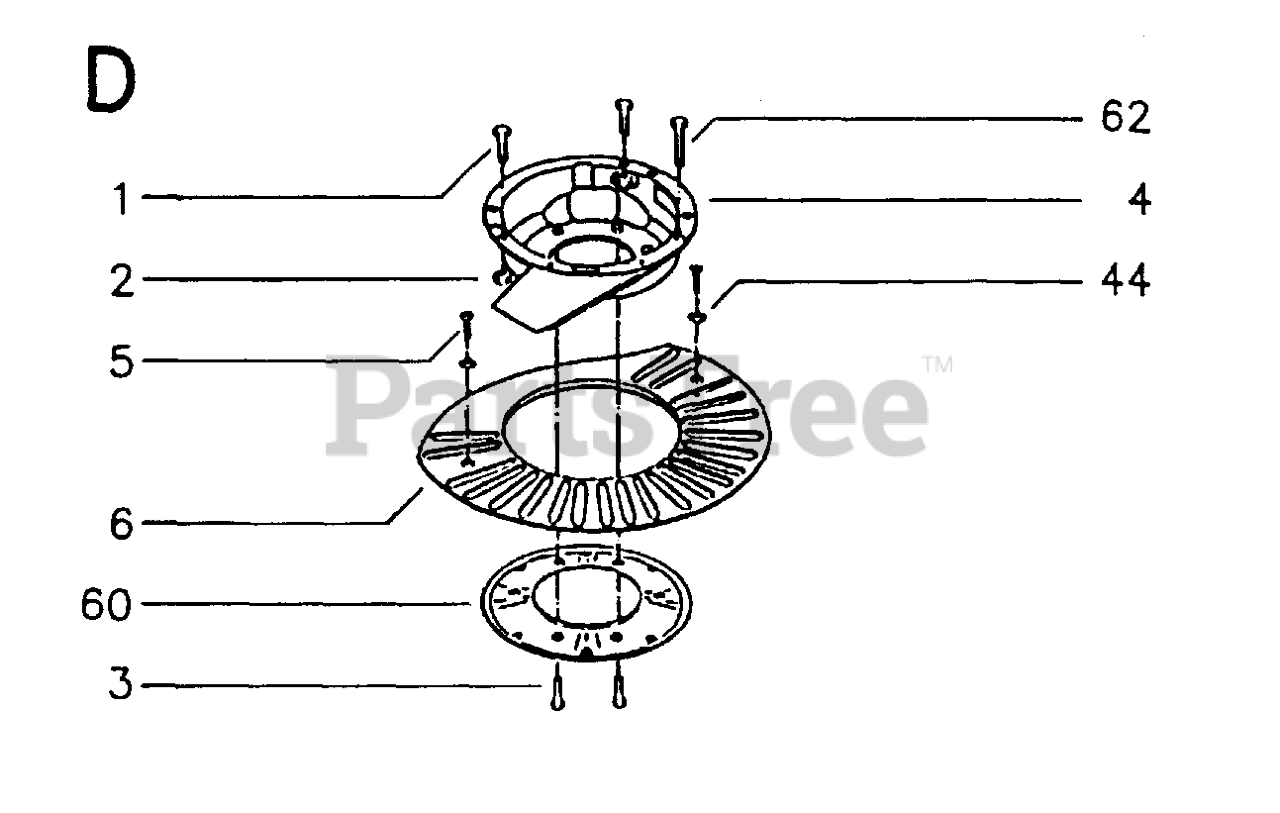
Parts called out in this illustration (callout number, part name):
2	LOCKNUT M8
4	REPL BY 516 69 84-11
6	CENTER PLATE
44	WASHER
